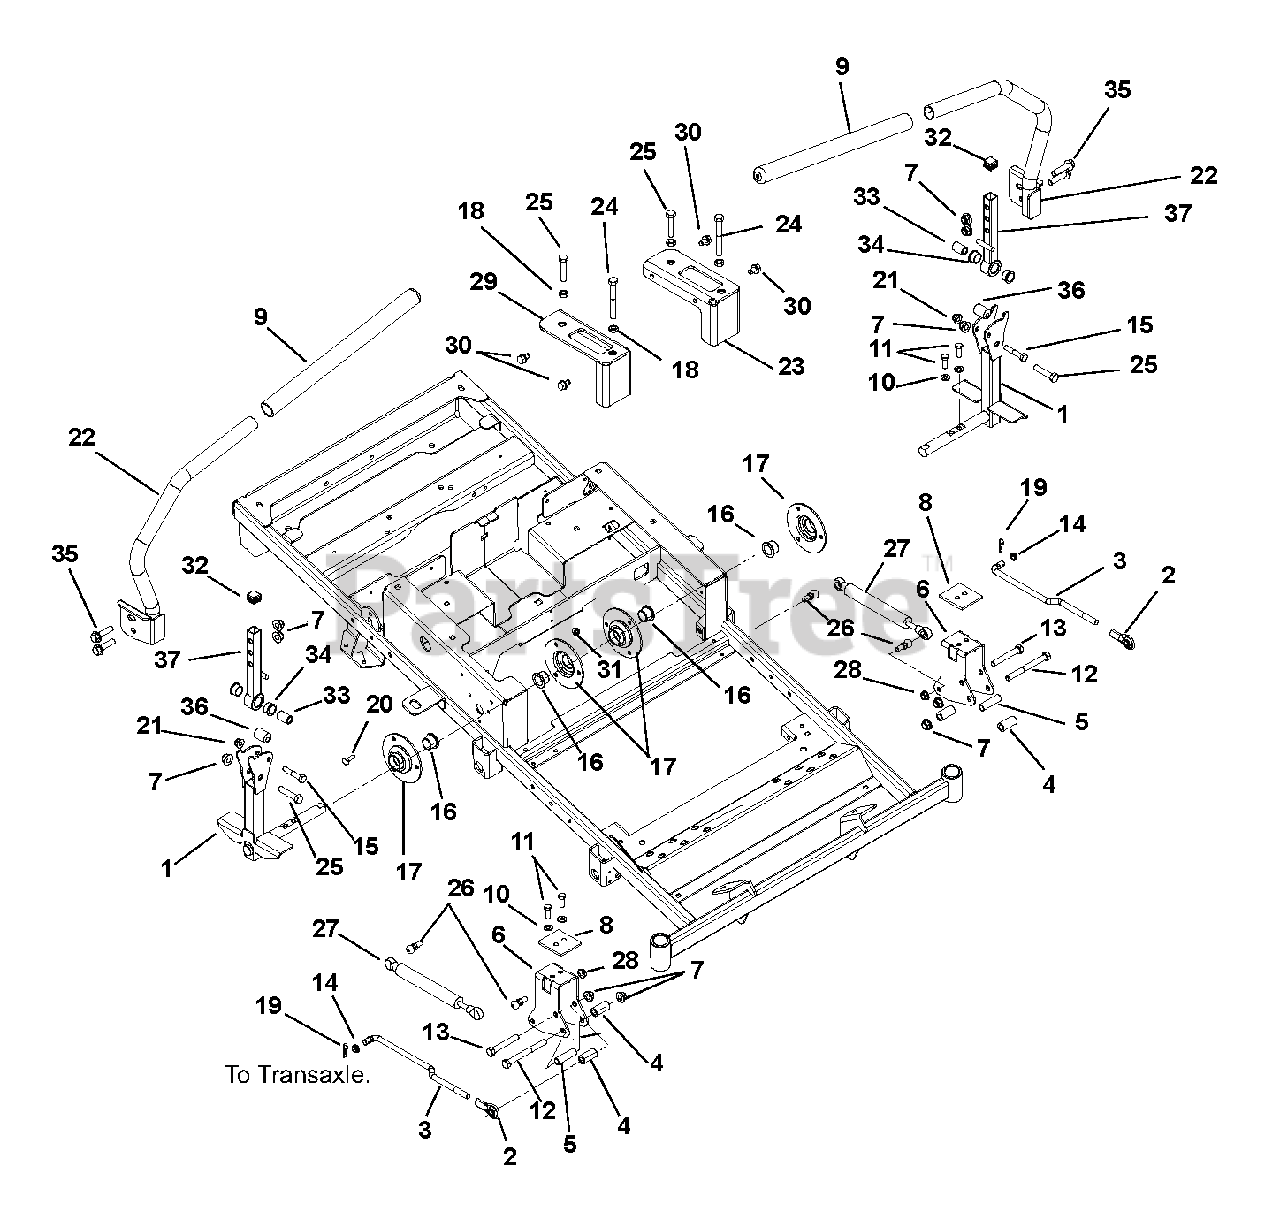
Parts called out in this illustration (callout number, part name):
1	WMT, CONTROL ARM
2	ROD END, .38 RH
3	LINK, TRANSMISSION
4	BSHG, SPCR .390X.625X1.25 PM
5	SPACER, STEERING
6	BRKT, STEERING
7	@NUT-LK-NYL-FLG .38-16 YWZC
8	PLATE, STEERING REINFORCING
9	GRIP, HANDLEBAR 15" FOAM
10	@WSHR-LK .31X.078 REG YWZC
11	BLT-HEX .31-18X1.00 GR8 YWZC
12	@BLT-HEX .38-16X3.75 GR5 YWZC
13	@BLT-HEX .38-16X2.50 GR5 YWZC
14	BUSHING, POLYLINER-.38 SNAPIN
15	@BLT-HEX .31-18X1.75 GR5 YWZC
16	BSHG-FLG .750X1.000X.625X1.250
17	BEARING FLANGE
18	NUT-HEX-JAM .375-16 YWZC
19	PIN-HAIR INT .08X.18X1.18 YWZC
20	@BLT-HEX .25-20X.75 GR5 YWZC
21	@NUT-LK-NYL-FLG .31-18 YWZC
22	WMT, STEERING HANDLE RH
23	BRACKET, LH SPEED CONTROL
24	BLT-HEX .38-16X3.00 GR5 FTH YZ
25	BLT-HEX .375-16X1.750 FTD YWZC
26	STUD- BALL
27	DAMPER, CONTROL
28	@NUT-LK-TOP-FLG .31-18 YWZC
29	BRACKET, RH SPEED CONTROL
30	@SCR-TAP .31-18X.50 HWH TR YWZ
31	@NUT-LK-TOP-FLG .25-20 YWZC
32	CAP PLUG, SQ 3/4-14-20 RIBBED
33	SPACER, .375X.625X.970 (PM)
34	BSHG-FLG, .625X.75X.450X.875
35	BOLT, SERRATED HEAD .38-16X1.5
36	BSHG, ECCENTRIC .328X.750X.970
37	WMT, UPPER CONTROL ARM
